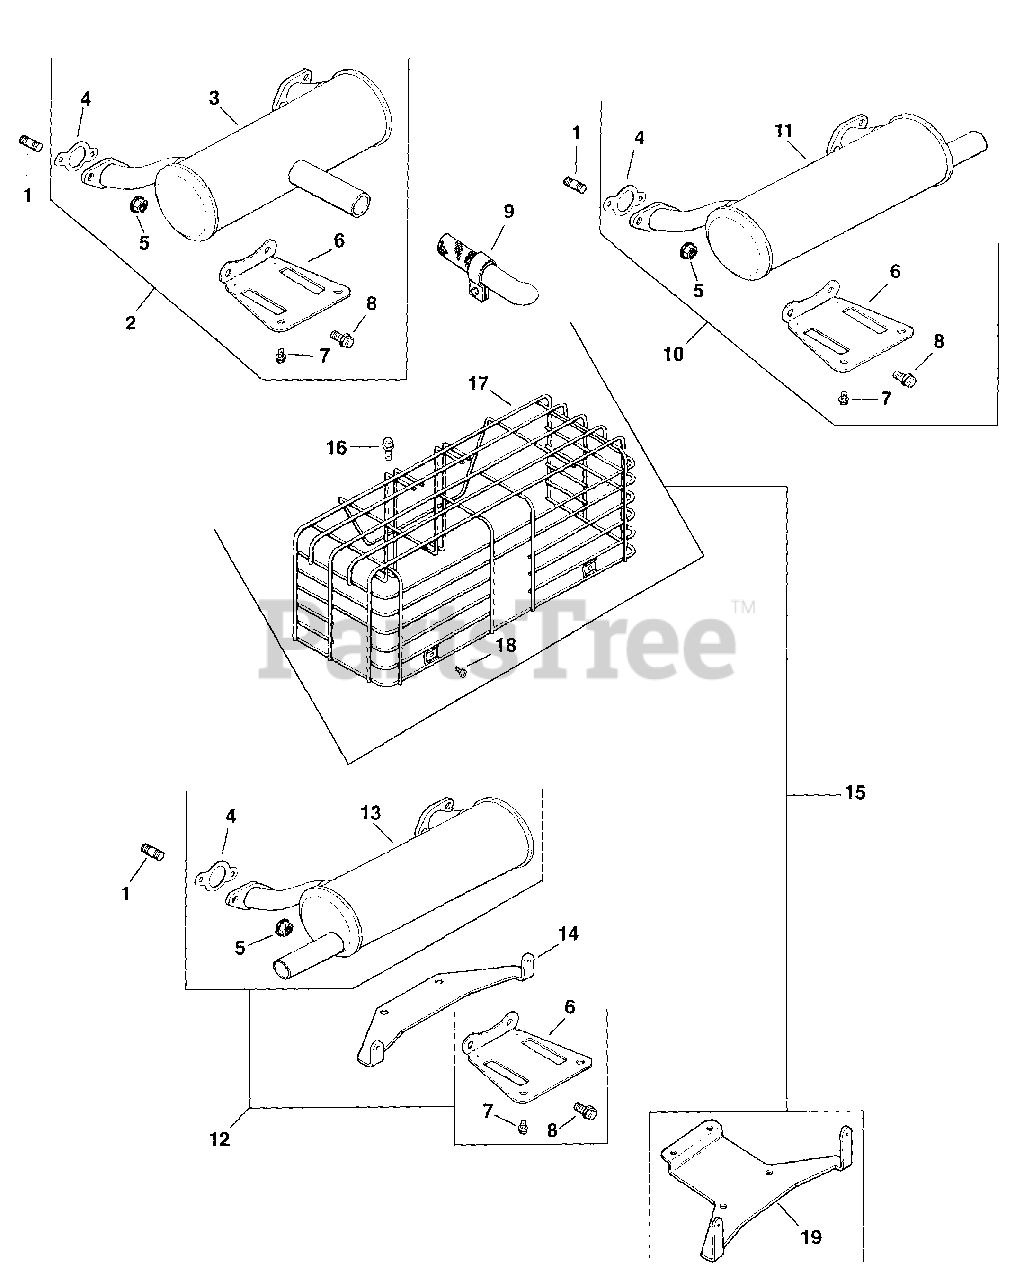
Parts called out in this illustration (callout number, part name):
1	STUD, EXHAUST (KM)-USE 25 072 24-S
3	MUFFLER, CENTER/STRAIGHT USE 24 068 131-S
5	NUT, FLG M8X1.25
6	BRACKET, MUFFLER
7	SCREW, FLG M6X1.0X12
8	SCREW, FLG M8X1.25X20
15	KIT, MUFFLER GUARD
16	SCREW,FLG THD FRM M5X0.8X16-(#25086398S)
17	GUARD, MUFFLER
18	SCREW, PHL PAN HD M5X0.8X10
19	BRACKET, EXHAUST GUARD
